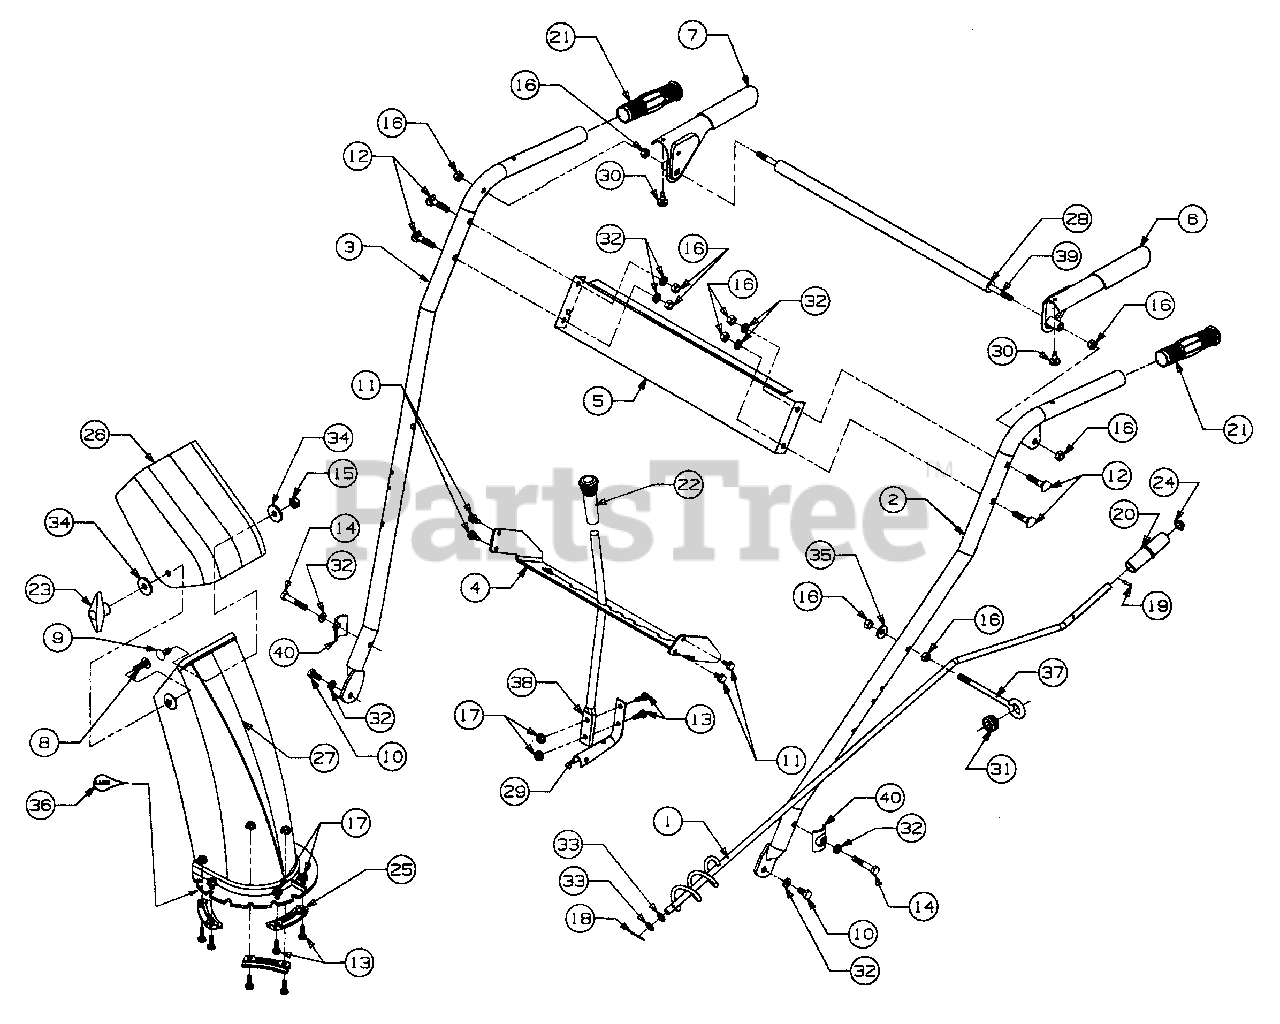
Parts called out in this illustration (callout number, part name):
1	Crank Chute
7	Lever, Clutch R.H.
8	Screw, Carriage
9	Bolt, Carriage
10	Hex Screw
11	Screw, Hex
12	Bolt, Curved Carriage
13	Hex Screw
14	Hex Screw
15	Nut, Hex Ctr. Lock
16	Nut, Hex
17	Nut, Lock, Hex, Flanged
18	Pin, Cotter
19	Roll Pin
20	Knob, Chute Crank
23	Knob, L/Wing Nut
24	Cap, Push
25	Chute, Flange Keeper
26	Chute, Upper 5.0 Dia.
27	Lower Chute, 5" Dia. Plastic
28	Tube, Pivot Rod Cover
29	Spring, Shift Lever
30	Bumper
31	Grommet
32	Lock Washer
33	Flat Washer
34	Washer
35	Washer, Bell
36	Lubricant
37	Eyebolt Chute Crank
39	Rod, Pivot
40	Handle Tab
